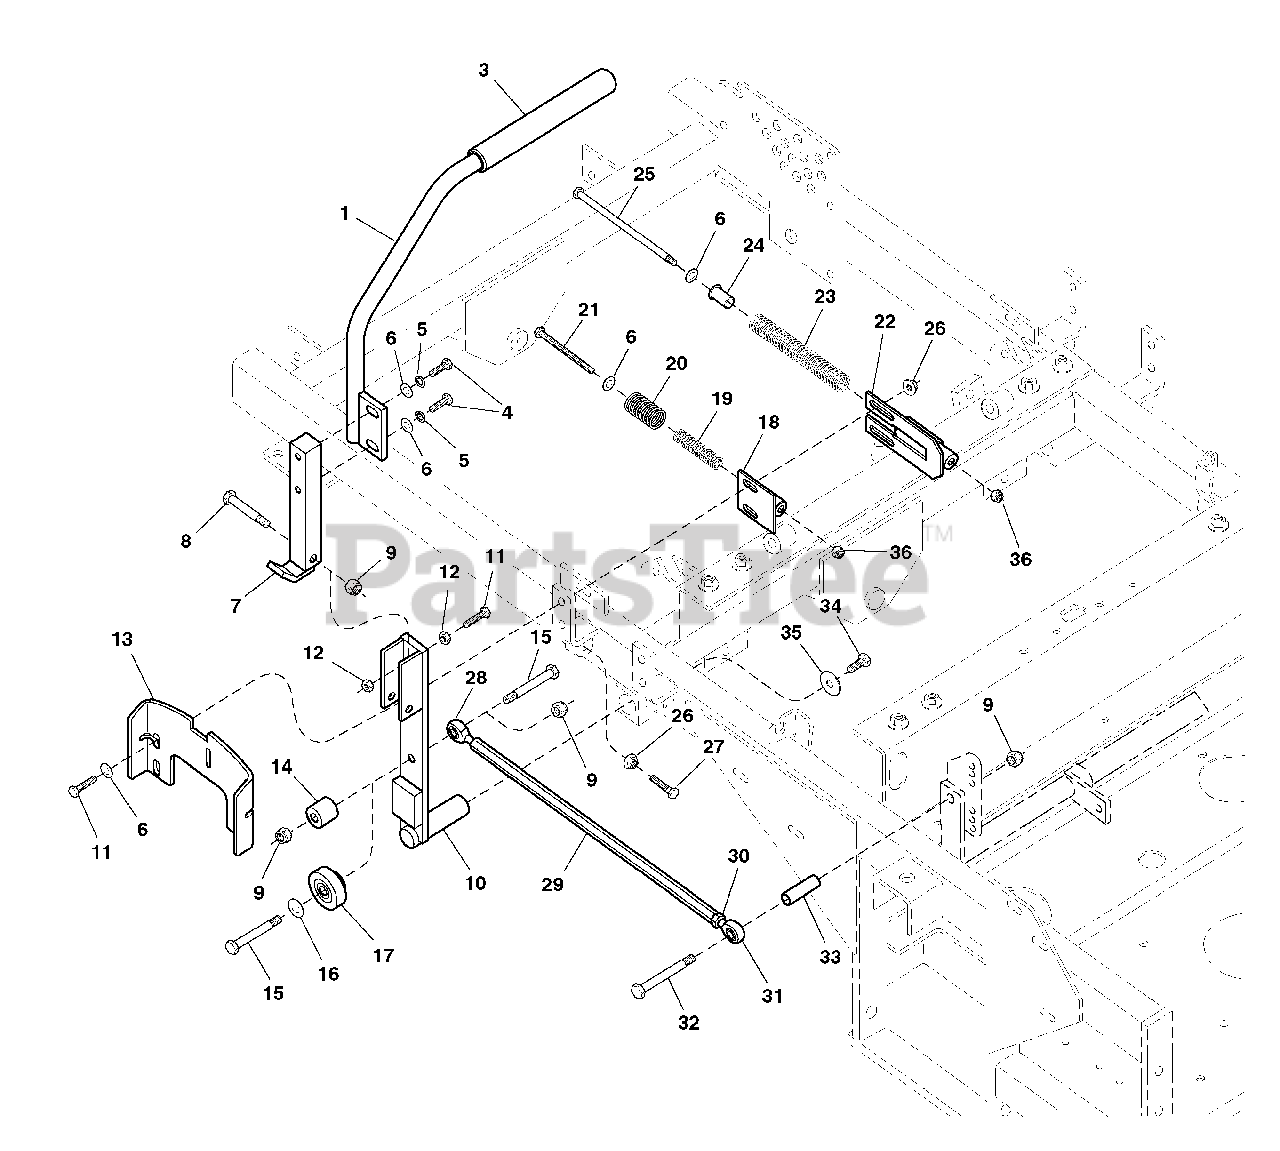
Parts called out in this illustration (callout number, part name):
1	MOTION CONTROL LEVER-LH
4	CAPSCREW, Hex Hd, 5/16-18 x 3/4
5	WASHER, Lock, 5/16
6	WASHER, 5/16
7	BASE, Control Lever
8	CAPSCREW, Hex Hd, 3/8-16 x 2
9	NUT, Hex, Nylon Lock, 3/8-16
10	MOTION CONTROL ARM
11	CAPSCREW, Hex Hd, 5/16-18 x 1
12	NUT, Hex, 5/16-18
13	NEUTRAL LOCK PLATE
14	SPACER (SN: 101-600 only)
15	CAPSCREW, Hex Hd, 3/8-16 x 2-1/4
16	WASHER, 3/8
17	BEARING & INSERT ASSEMBLY, Complete (SN: 601 & up)
18	REVERSE SPRING MOUNT (SN: 101-300 only)
19	SPRING, Compression (SN: 101-300 only)
20	SPRING, Compression (SN: 101-300 only)
21	CAPSCREW, Hex Hd, TFL, 5/16-18 x 3-1/2 (SN: 101-300 only)
22	REVERSE SPRING MOUNT
23	SPRING, Compression
24	BUSHING, Flange
25	CAPSCREW, Hex Hd, 5/16-18 x 7
26	NUT, Hex, Serrated Flange, 5/16-18
27	CAPSCREW, Hex Hd, 5/16-18 x 1-1/4
28	BALL JOINT, 3/8, LH
29	HEX ROD, Long
30	NUT, Hex, 3/8-24
31	BALL JOINT, 3/8
32	CAPSCREW, Hex Hd, 3/8-16 x 3
34	CAPSCREW, Hex Hd, Loctite Patch, 3/8-16 x 3/4
35	WASHER, Fender, 3/8
36	NUT, Hex, Nylon Lock, 5/16-18
